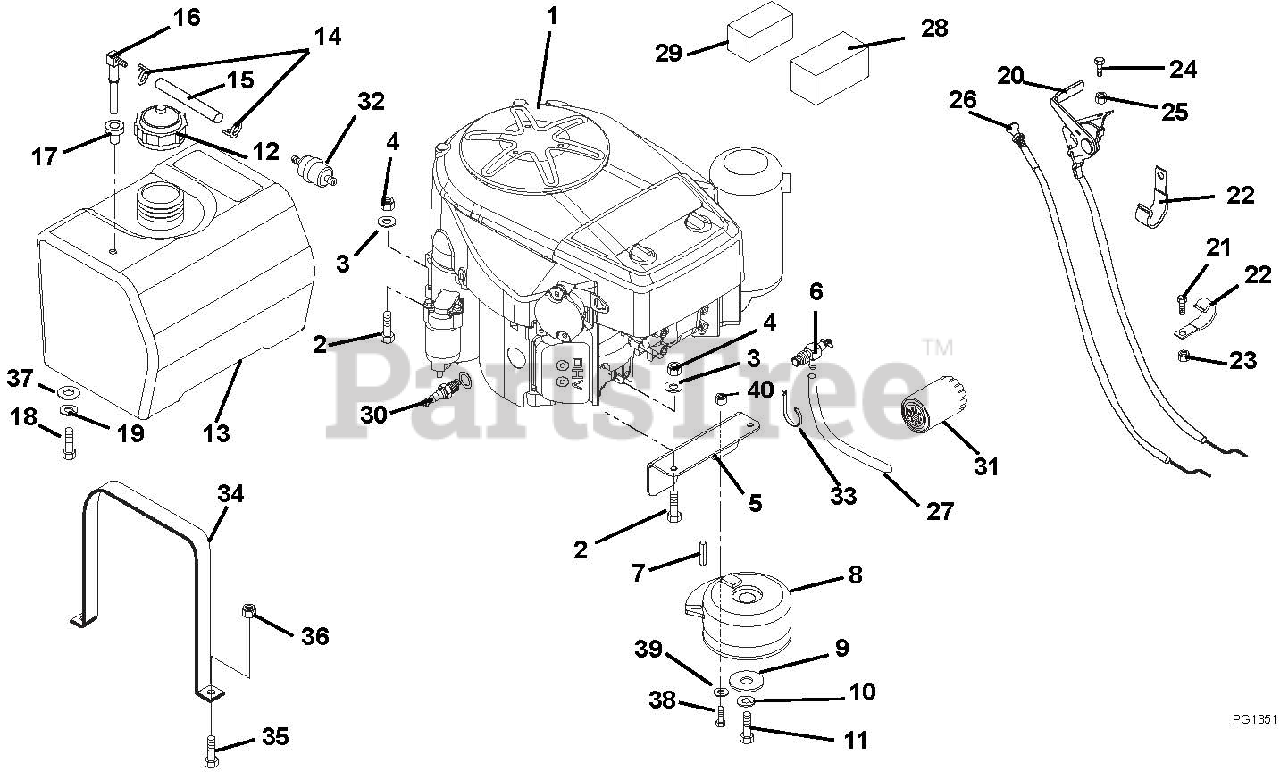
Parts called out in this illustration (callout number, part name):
1	Engine, 15 HP Kawasaki FH430V - AS02
1	Engine, 13 HP Kawasaki
2	Bolt-Hex .31-18 x 1.75 Grade 5
3	Washer-Locking .31 x .078 Regular
4	Nut-Hex .31-18
5	Bracket, Clutch
6	Valve, Oil Drain
7	Key-Square .25 x 1.25 x 25 SAE 8630 OR SAE 1035
7	Key, Square .25 x .25 x 1.00 RC 40-50
8	Clutch, Electric PTO
9	Washer-Flat-Steel .469 x 2.00 x .25
10	Washer-Locking .44 x .109 Regular
11	Bolt-Hex .44-20 x 3.00 Grade 5
11	Bolt-Hex .44-20 x 2.50 Grade 5
12	Cap, Fuel
13	Tank, Fuel
14	Clamp-Hose Wire .49/.51 x .116
15	Gas Line-Bulk .25 I.D.
16	Fitting, Tank
17	Bushing
17	Grommet
18	Bolt-Hex .38-16 x .75 Grade 5
19	Washer-Locking .38 x .094 Regular
20	Cable, Throttle-with Liner
20	Cable- Throttle-with Liner
21	Bolt-Hex .31-18 x .75 Grade 5
23	Nut-Locking-Nylon .312-18
24	Screw-Machine 10-24 x .75 Hex Washer Head
25	Nut-Locking-Nylon 10-24 with Insert
26	Control, Choke
27	Tube, Oil Drain
28	Filter, Air Paper
29	Filter, Air Foam
30	Spark Plug
31	Filter, Oil
32	Fuel Filter- Kawasaki
33	Cable Tie
34	Tank Strap
35	Bolt, Round Head Square Neck .25-20 x .75 Grade 5
36	Nut, Locking Nylon .25-20
37	Washer, Flat Steel .409 x .812 x .065
38	Bolt, Hex .31-18 x 1.25 Grade 5
39	Washer, Flat-Steel .344 x .688 x .065
40	Nut, Locking-Center .31-18
